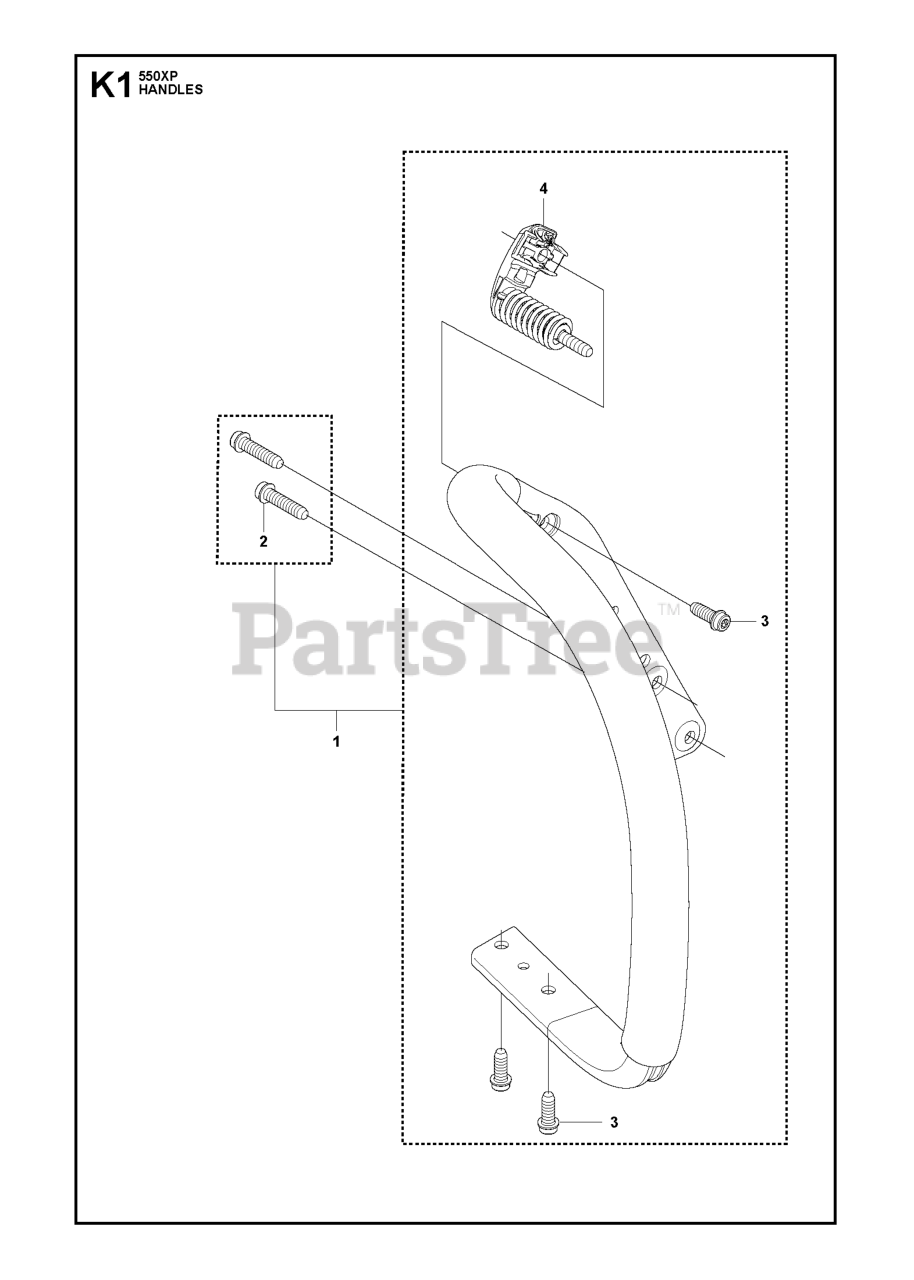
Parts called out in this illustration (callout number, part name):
1	FRONT HANDLE
3	SCREW ITXSCFT PL6X16 T27 10.9
4	ANTIVIBRATION ELEMENT
